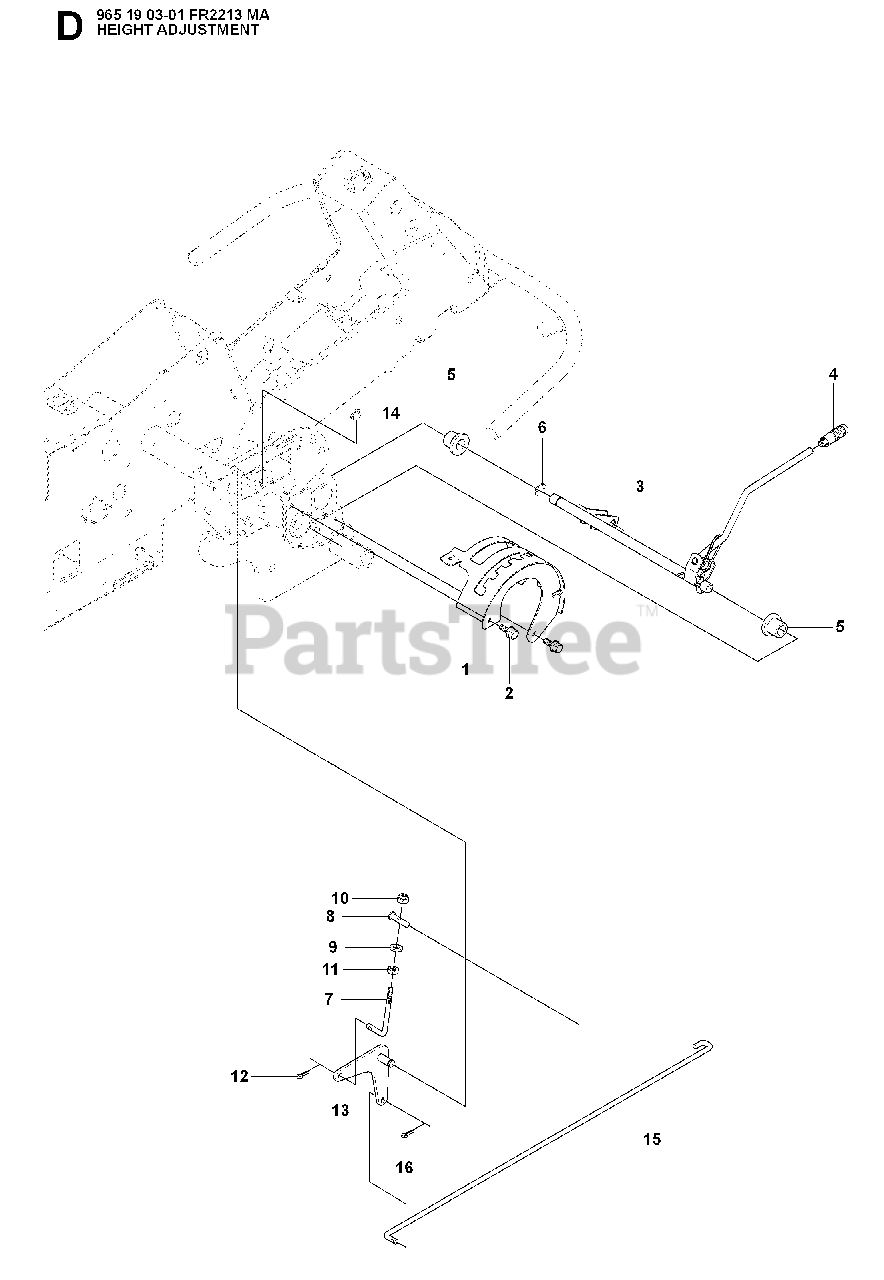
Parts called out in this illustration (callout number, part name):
4	GEAR STICK KNOB
5	BUSHING
9	WASHER
10	LOCKNUT M8
11	NUT
12	SPLIT PIN
14	RETAINING RING
16	SPLIT PIN
